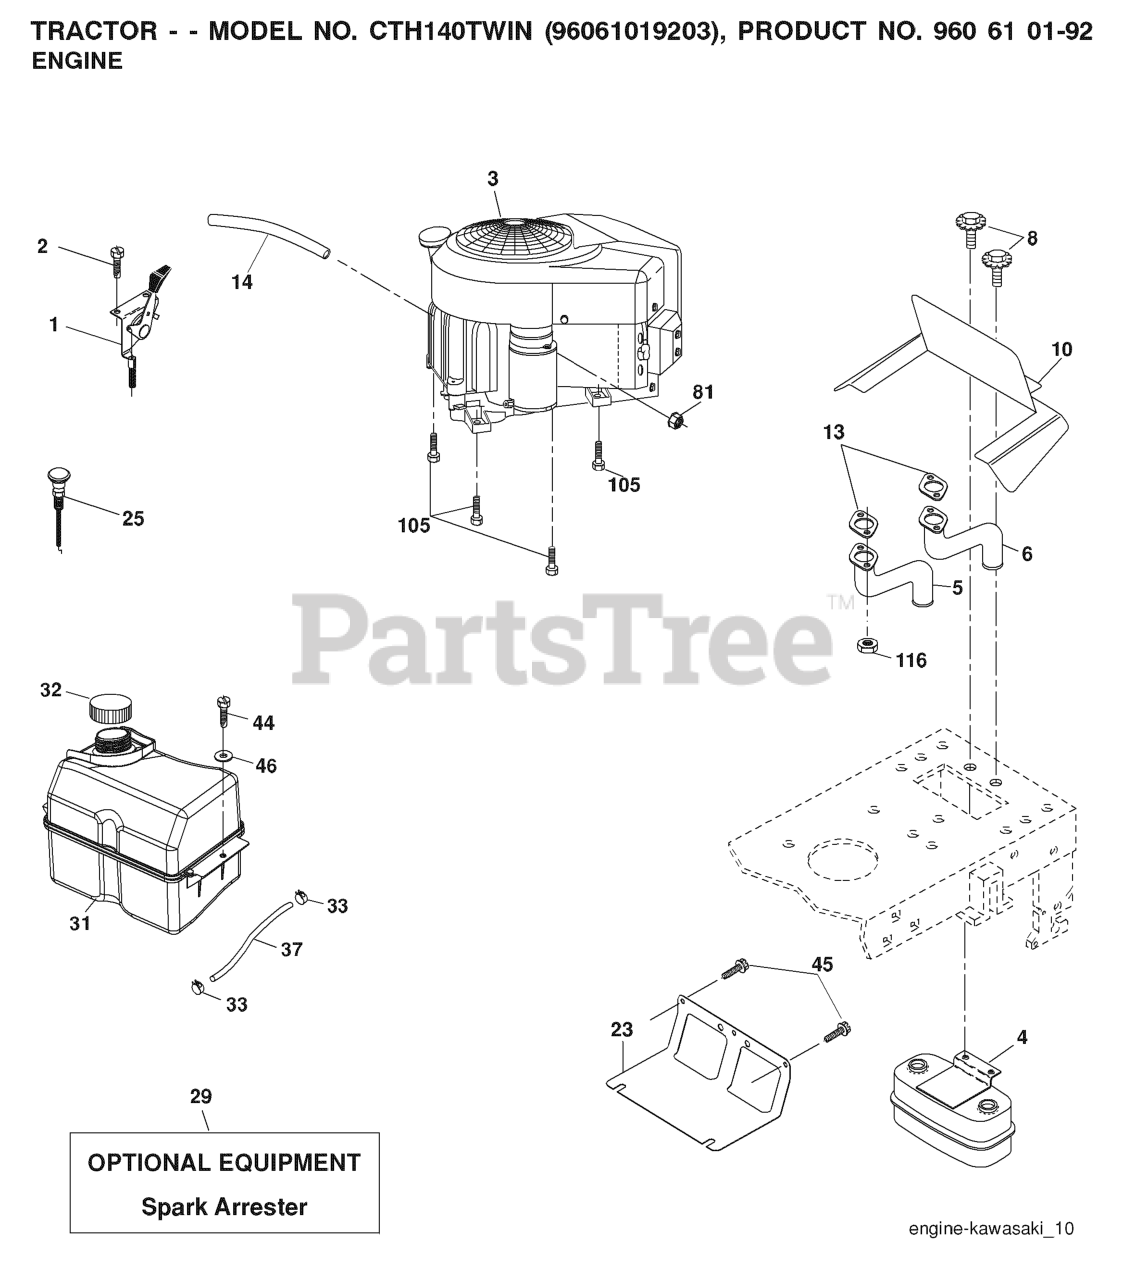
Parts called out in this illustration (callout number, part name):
1	CONTROL.THROTTLE.COBRA.BLACK
2	SCREW.#10 X 0.750.BOS
4	MUFFLER.TWIN.CYL.LOW.TONE
5	EXHAUST.TUBE.LH.KAWASAKI.
6	EXHAUST.TUBE.RH.KAWASAKI.
8	BOLT.5/16-18UNCX3/4 W/SEMS.BLK
10	RP SHIELD HEAT MUFFLER
14	TUBE, DRAIN OIL ASM.
23	SHIELD.BROWNING.DBR.GUARD
25	CONTROL.CHOKE.ERGO.PUSH-IN.BLA
29	KIT.SPARK ARRESTOR 794945 B&S
31	RP TANK FUEL FRT 1.5 GAL
32	FUEL CAP
33	HOSE CLAMP
37	LINE.FUEL.20
44	SCREW HEXWSHR 1/4-20X3/4
45	SCREW, 3/8-16X3/4
81	NUT
105	SCREW 3/8-16X1
116	NUT.HEX.FLANGE.TOPLOCK
